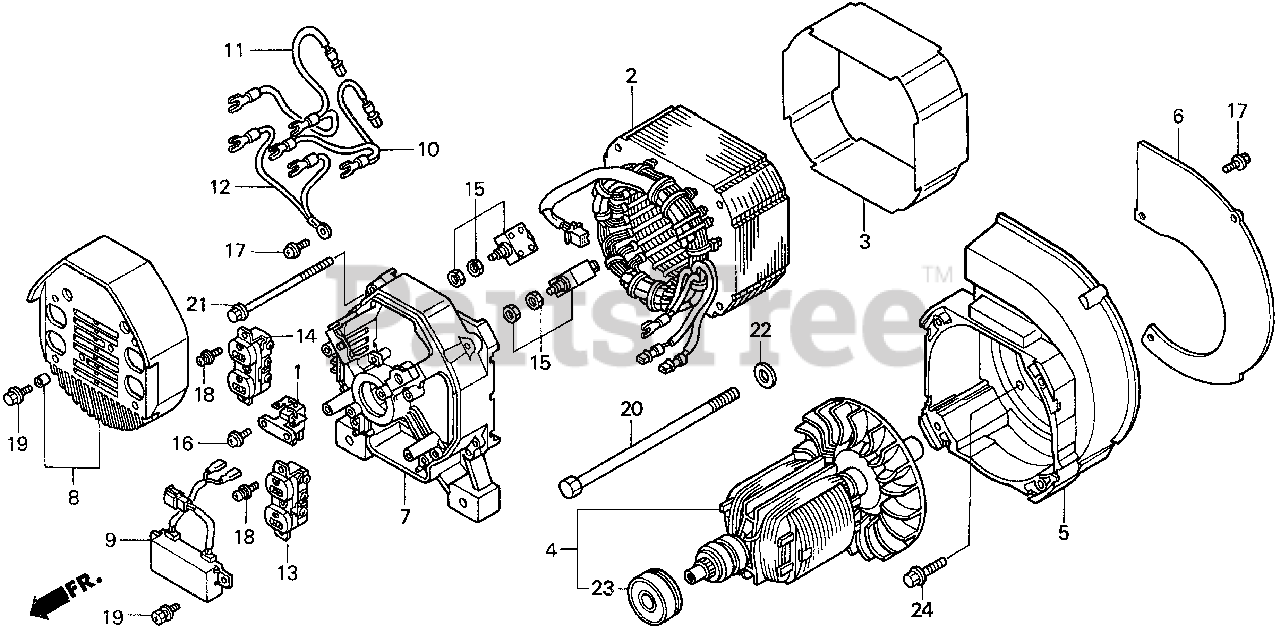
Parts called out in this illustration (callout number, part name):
1	BRUSH ASSY.
2	STATOR ASSY.
3	COVER, STATOR
5	HOUSING, FR.
6	PLATE, HOUSING
7	HOUSING, RR.
8	COVER, GENERATOR END (A)
9	REGULATOR ASSY., AUTOMATIC VOLTAGE
10	WIRE A, TERMINAL
11	WIRE B, TERMINAL
12	WIRE, GROUND
13	RECEPTACLE (20A-125V)
14	RECEPTACLE (20A-250V)
15	PROTECTOR, CIRCUIT (13A)
16	SCREW, TAPPING (5X18)
17	SCREW, TAPPING (5X12)
18	SCREW, TAPPING (4X10)
19	SCREW, TAPPING (5X14)
20	BOLT, HEX. (10X270)
21	BOLT, FLANGE (6X90)
22	WASHER (10.5MM)
23	BEARING ASSY. (6204)
24	BOLT, FLANGE (8X20)
